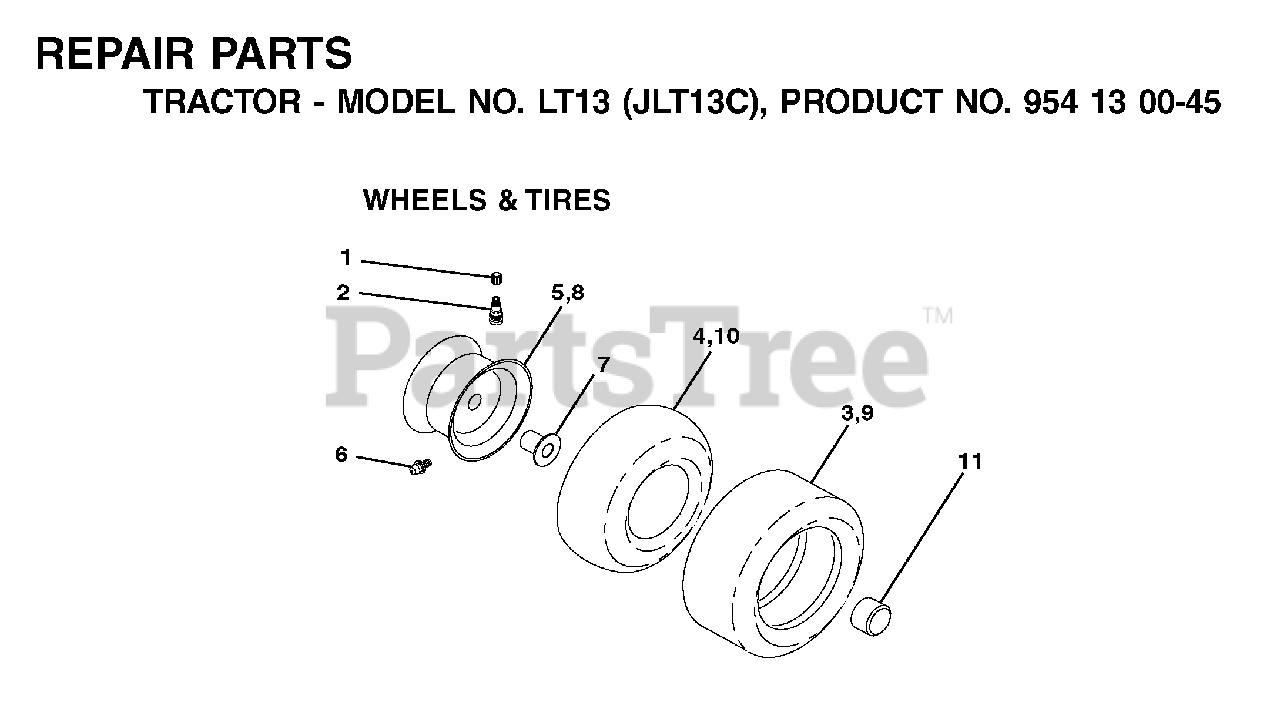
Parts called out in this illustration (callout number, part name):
1	VALVE CAP
2	VALVE STEM LT
3	TIRE HEAVY DUTY
4	TUBE.5.3/4.5/6
5	RIM ASM 6" FRONT SILVER
6	FITTING LT
7	BEARING T
8	RIM ASM 8" REAR SILVER
9	TIRE
10	TUBE
11	CAP, AXLE BLK
